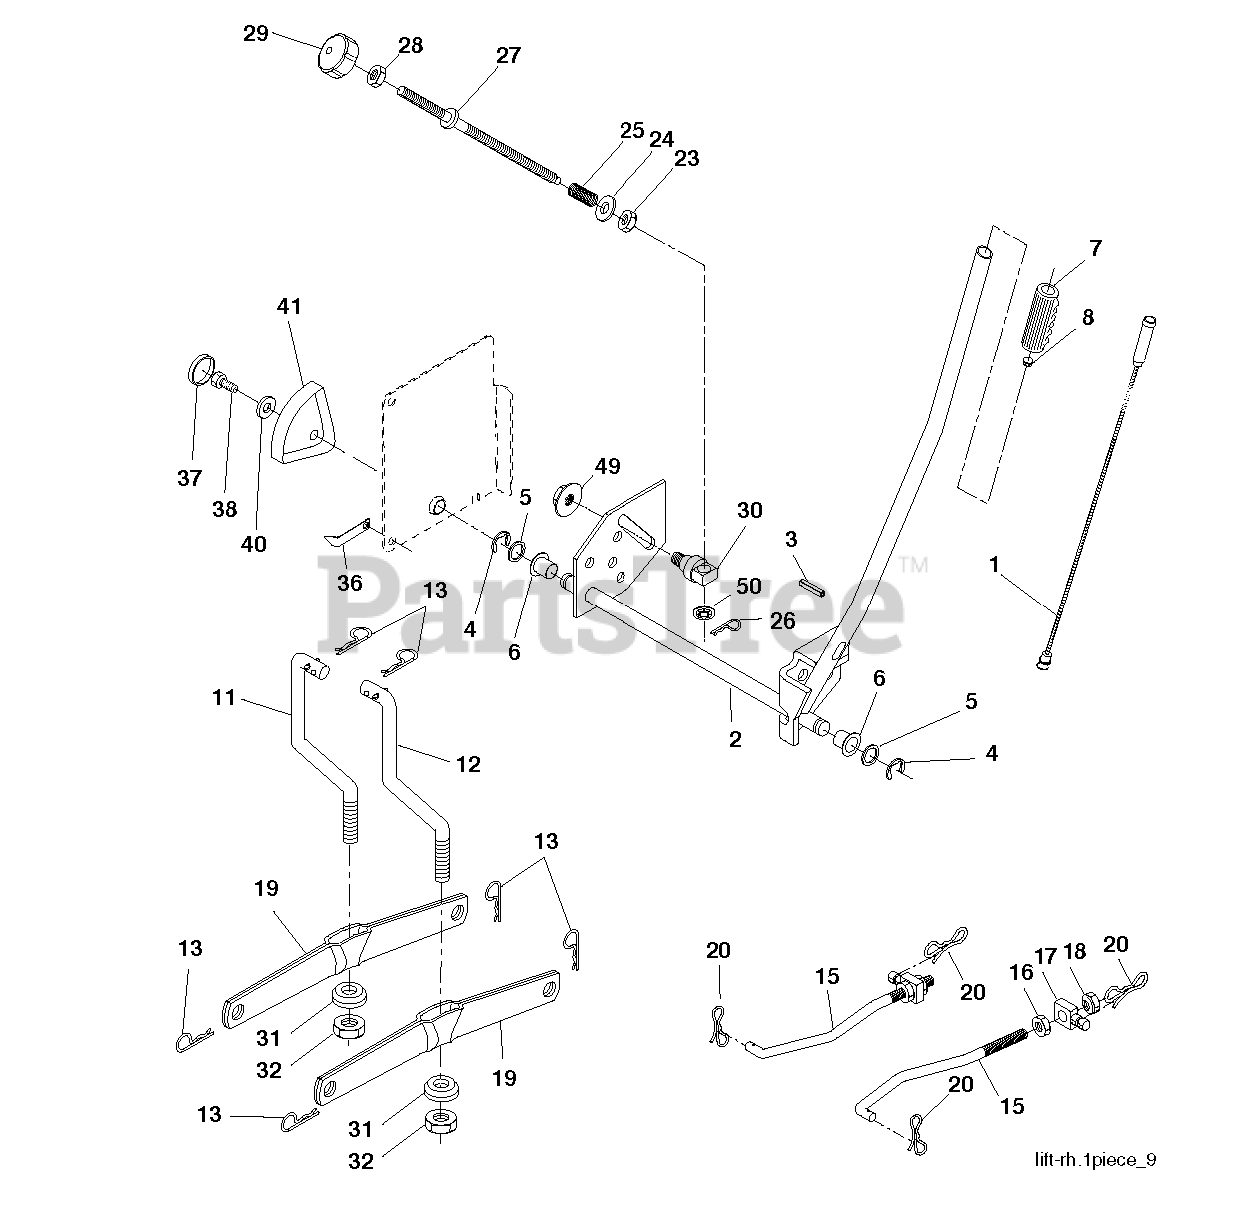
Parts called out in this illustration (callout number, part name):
1	PLUNGER.ASM.LIFT.LVR.BLK.17.32
2	SHAFT ASM R HANDLE
3	PIN GROOVE.
4	RETAINING RING LT
6	BEARING.NYLON
8	PLUNGER BUT KIT
11	LINK
12	LINK
13	RETAINER-SPRNG RB
15	LINK.SUSPENSION.FRONT
16	NUT.HEX.JAM.1/2-13
18	NUT.LK.W/WSH.1/2.
19	ARM.REAR.SUSPENSION
20	PIN.COTTER.7/16.BOW TI.
25	SPRING**
26	RETAINER CLIP
27	ROD ADJ LIFT
28	NUT
29	KNOB INF 3/8-16
31	BEARING.PIVOT.LIFT
32	NUT CROWNLOCK 3/8-24
36	POINTER, HEIGHT INDICATOR(2 2)
38	SCREW 5/16-18X1
41	HEIGHT INDICATOR
49	NUT
50	NUT PUSH M
